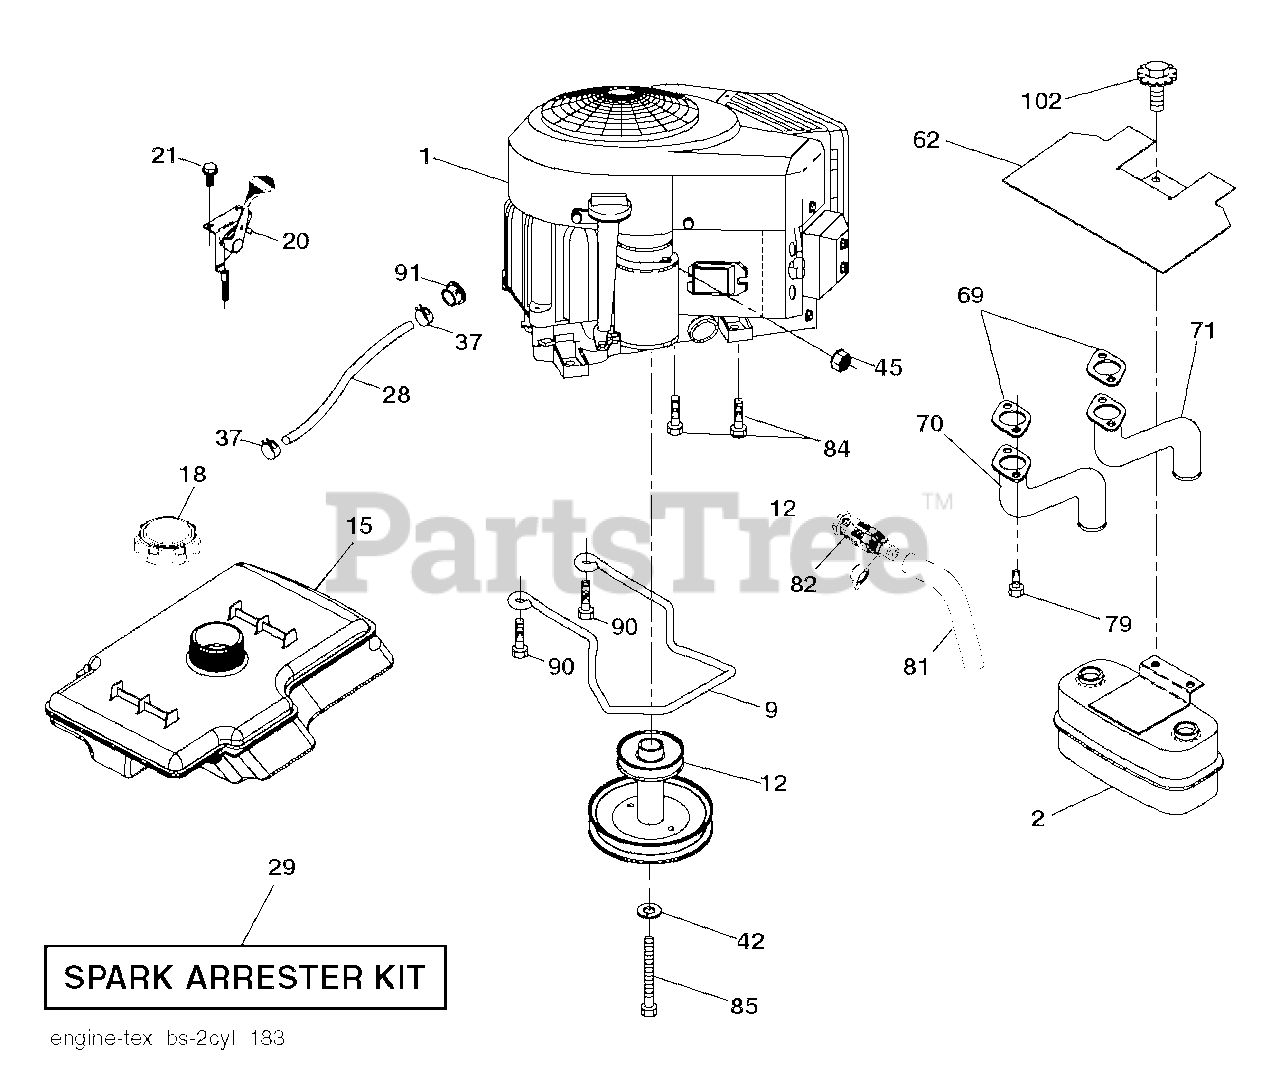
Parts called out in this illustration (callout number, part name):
2	MUFFLER.ASM.TWN.EXTNDED.DFLCTR
9	KEEPER.BELT.ENG.3.25"2BOLT.PNT
12	PULLEY.ENGINE.5.0.PD
18	Fuel Tank Cap Assembly, 3" N-EPA Black
20	CONTROL.TH/CK.COBRA.B&S.TWN.
21	SCREW.#10 X 0.750.BOS (2 2)
28	HOSE.1/4".FUEL.LINE.64".LENGTH
29	KIT.SPARK ARRESTOR(392390 B&S)
37	HOSE CLAMP
42	LOCKWASHER
45	NUT
62	SHIELD.HEAT.MUFFLER
69	GASKET.MUFFLER
70	EXHAUST.TUBE.LH.BS/TWIN
71	EXHAUST.TUBE.RH.B&S.TWIN.INTEK
79	SCREW.SOCKET.HEAD.5/16-18
81	TUBE, DRAIN OIL ASM.
82	VALUE.OIL.DRAIN
84	SCREW.3/8-16
85	Hex Bolt, 7/16-20 X 4-1/4" Grade 5
90	SCREW 3/8-16X1
91	BUSHING.1.375OD
102	SCREW
